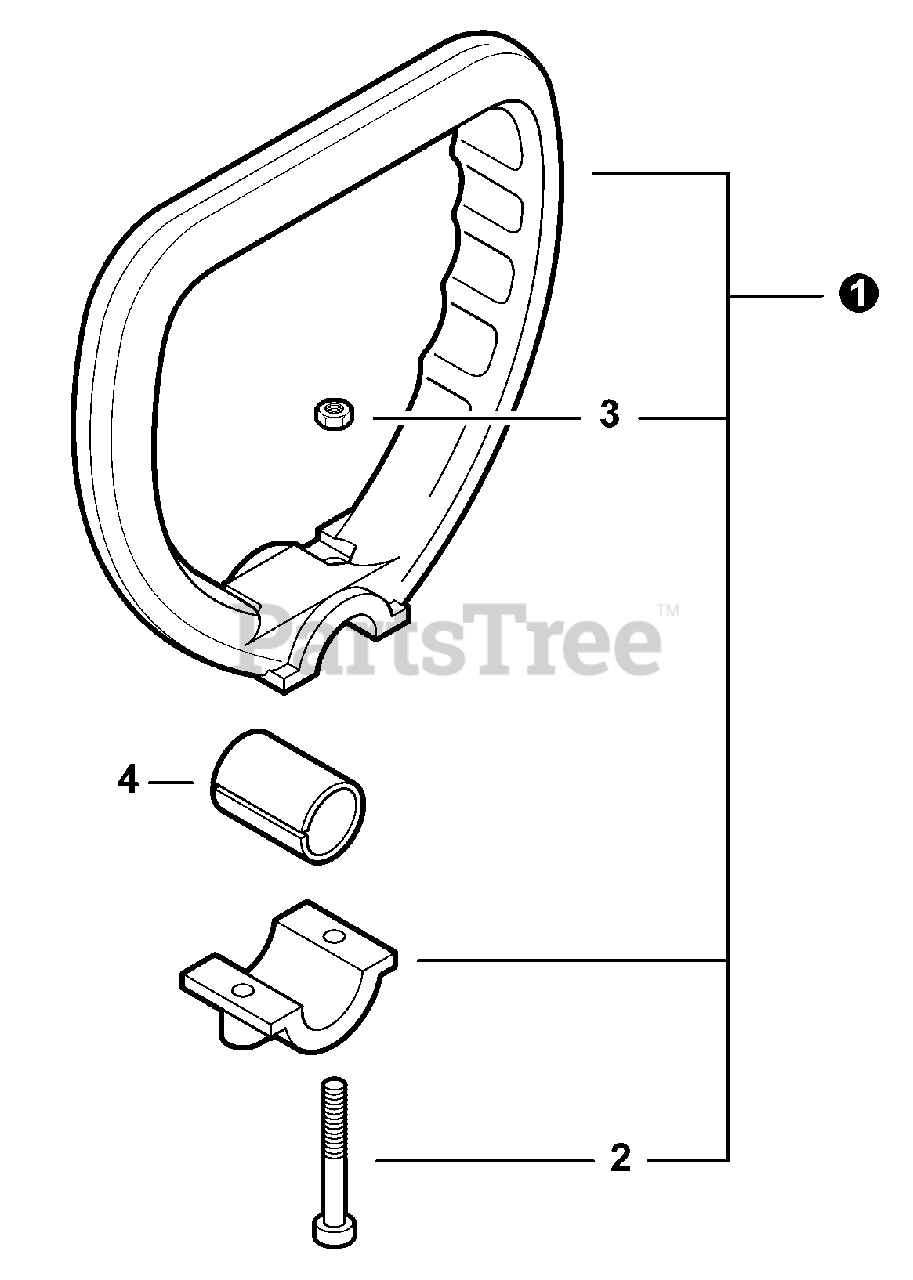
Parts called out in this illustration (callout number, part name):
1	HANDLE ASSY - SUPPORT
2	BOLT, TORX 5×35
3	NUT - 5
